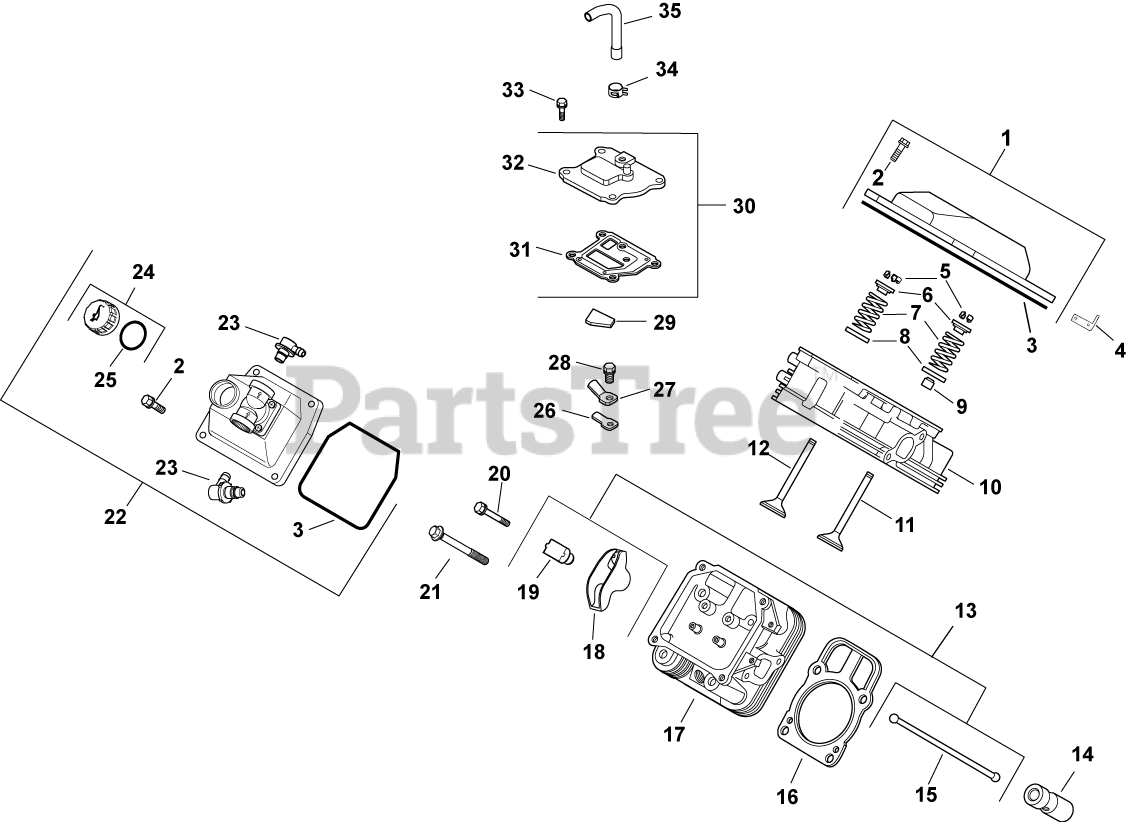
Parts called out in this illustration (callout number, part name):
1	KIT, VALVE COVER-PLAIN
2	SCREW, FLG M6X1.0X30
3	O-RING (YELLOW) -USE 24 153 30-S
4	STRAP, LIFTING-USE 25 445 03-S
5	KIT, RETAINER
6	RETAINER, VALVE SPRING - USE 25 173 28-S
7	SPRING, VALVE
8	RETAINER, SPRING
9	SEAL, VALVE STEM - (#2503214S)
10	KIT, HEAD #1
11	VALVE, INTAKE (STD)
12	VALVE, EXHAUST (STD) - USE 32 016 01-S
13	KIT, VALVE TRAIN
14	LIFTER, HYDRAULIC VALVE-USE 25 351 10-S
15	ROD, PUSH
16	CYL HEAD GASKET KIT-USE 24 841 04-S
17	HEAD ASSEMBLY, #2 CYLINDER
18	ARM, ROCKER
19	PIVOT, ROCKER ARM
20	SCREW, FLG M6X1.0X34
21	SCREW - USE 62 086 08-S
22	KIT, VALVE COVER-FUEL PUMP
23	KIT, 90 DEG. FITTING
24	CAP ASSY, OIL FILL (YELLOW)
25	O-RING-USE 24 153 32-S
26	REED, BREATHER
27	RETAINER, REED
28	SCREW, FLG THD FRM M5X.8X10
29	FILTER, BREATHER-USE 24 050 11-S
30	KIT, BREATHER ASSEMBLY
31	GASKET, BREATHER-USE 24 041 67-S
32	COVER, BREATHER -USE 24 033 01-S
33	SCREW,FLG THD FRM M6X1.0X20-(#25086396S)
34	CLAMP, HOSE (KM)-USE 25 237 31-S
35	HOSE, BREATHER
2401602-S	VALVE, EXHAUST (.25)
2401702-S	VALVE, INTAKE (.25)
